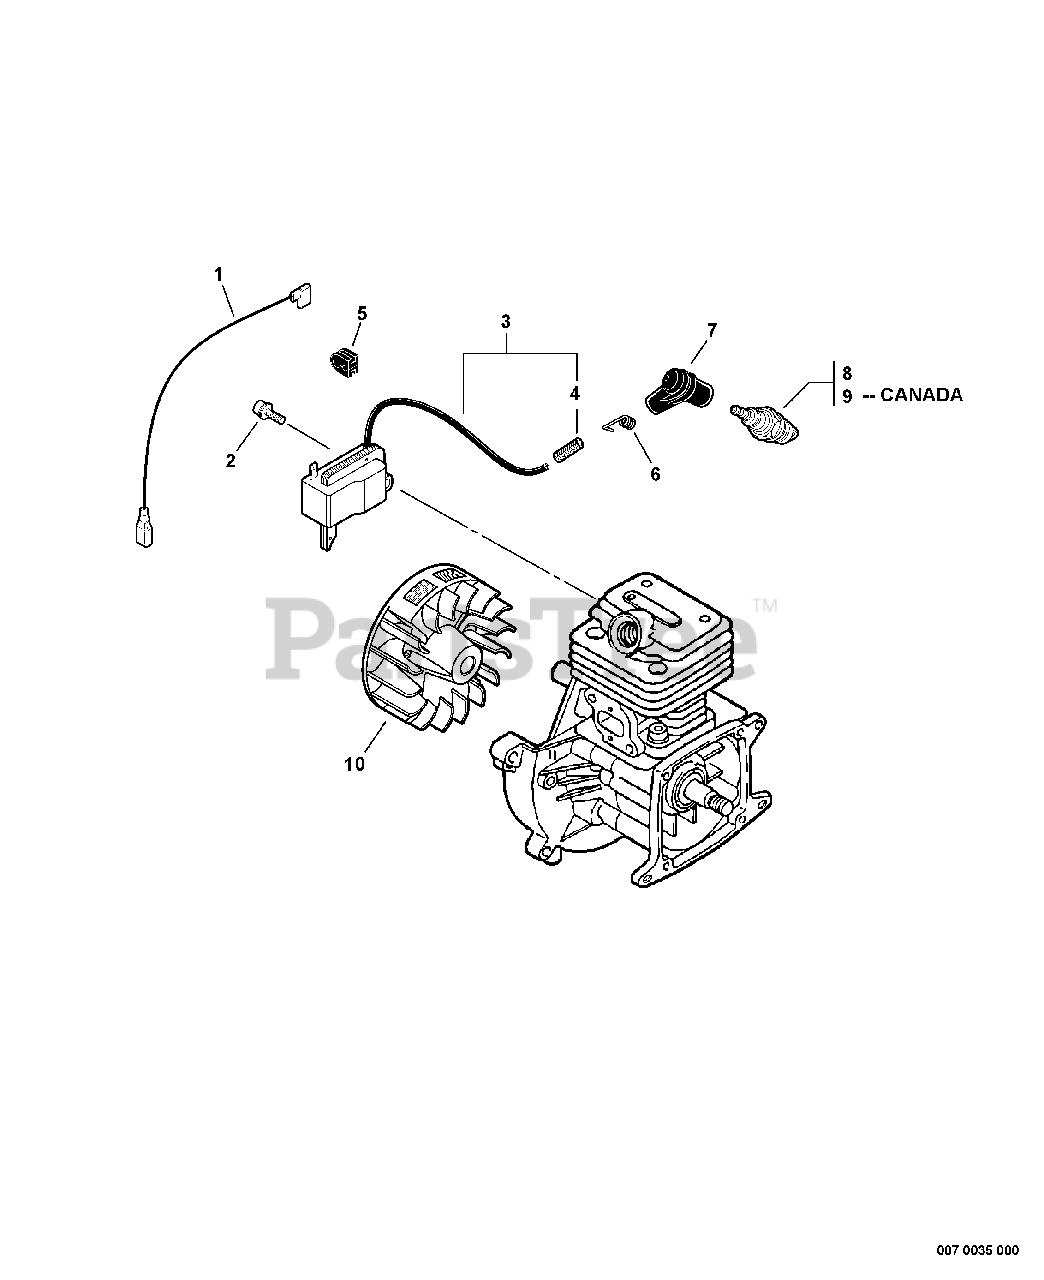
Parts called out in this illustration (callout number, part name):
1	LEAD - IGNITION
2	SCREW - 5X16
3	COIL, IGNITION
4	TUBE, INSULATOR
6	TERMINAL, SPARK PLUG CAP
7	CAP, SPARK PLUG
8	SPARK PLUG -- BPM-8Y
9	SPARK PLUG -- BPMR-8Y
10	FLYWHEEL
